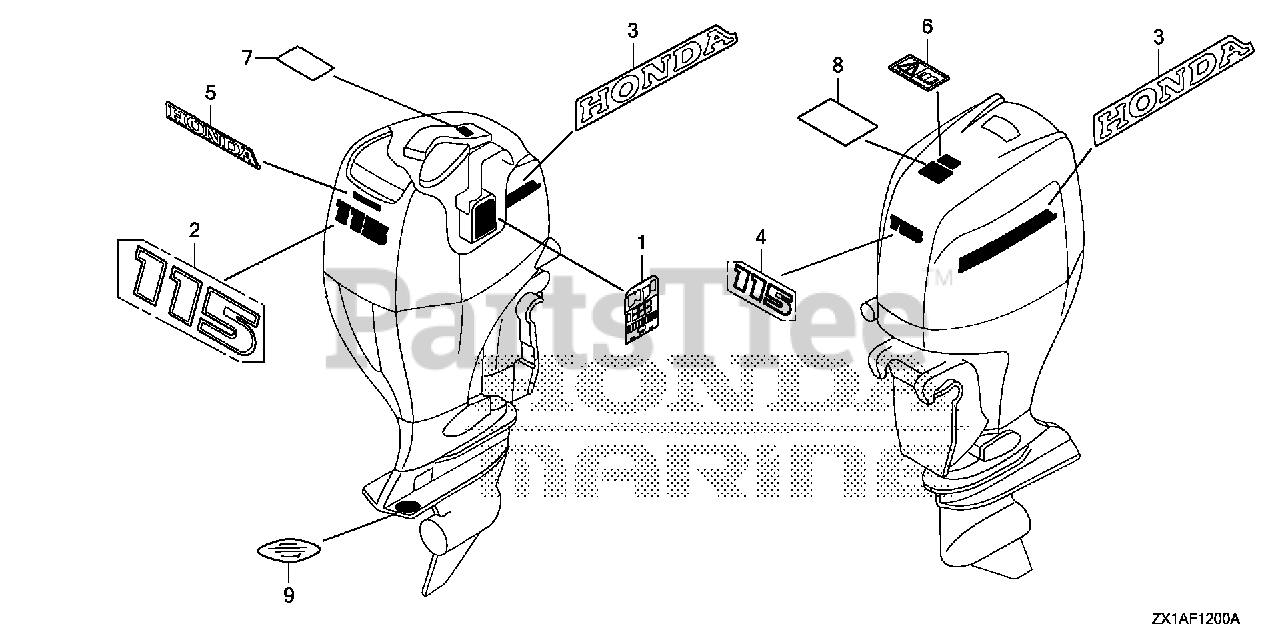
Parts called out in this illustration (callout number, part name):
1	LABEL, FUSE
2	MARK, RR. (115)
3	MARK, SIDE STRIPE
4	MARK, FR. EMBLEM (115)
5	MARK, HONDA
7	LABEL, OIL CAUTION (E)
8	LABEL, WARNING OPERATOR (ENGLISH)
9	MARK, COUNTER ROTATION
